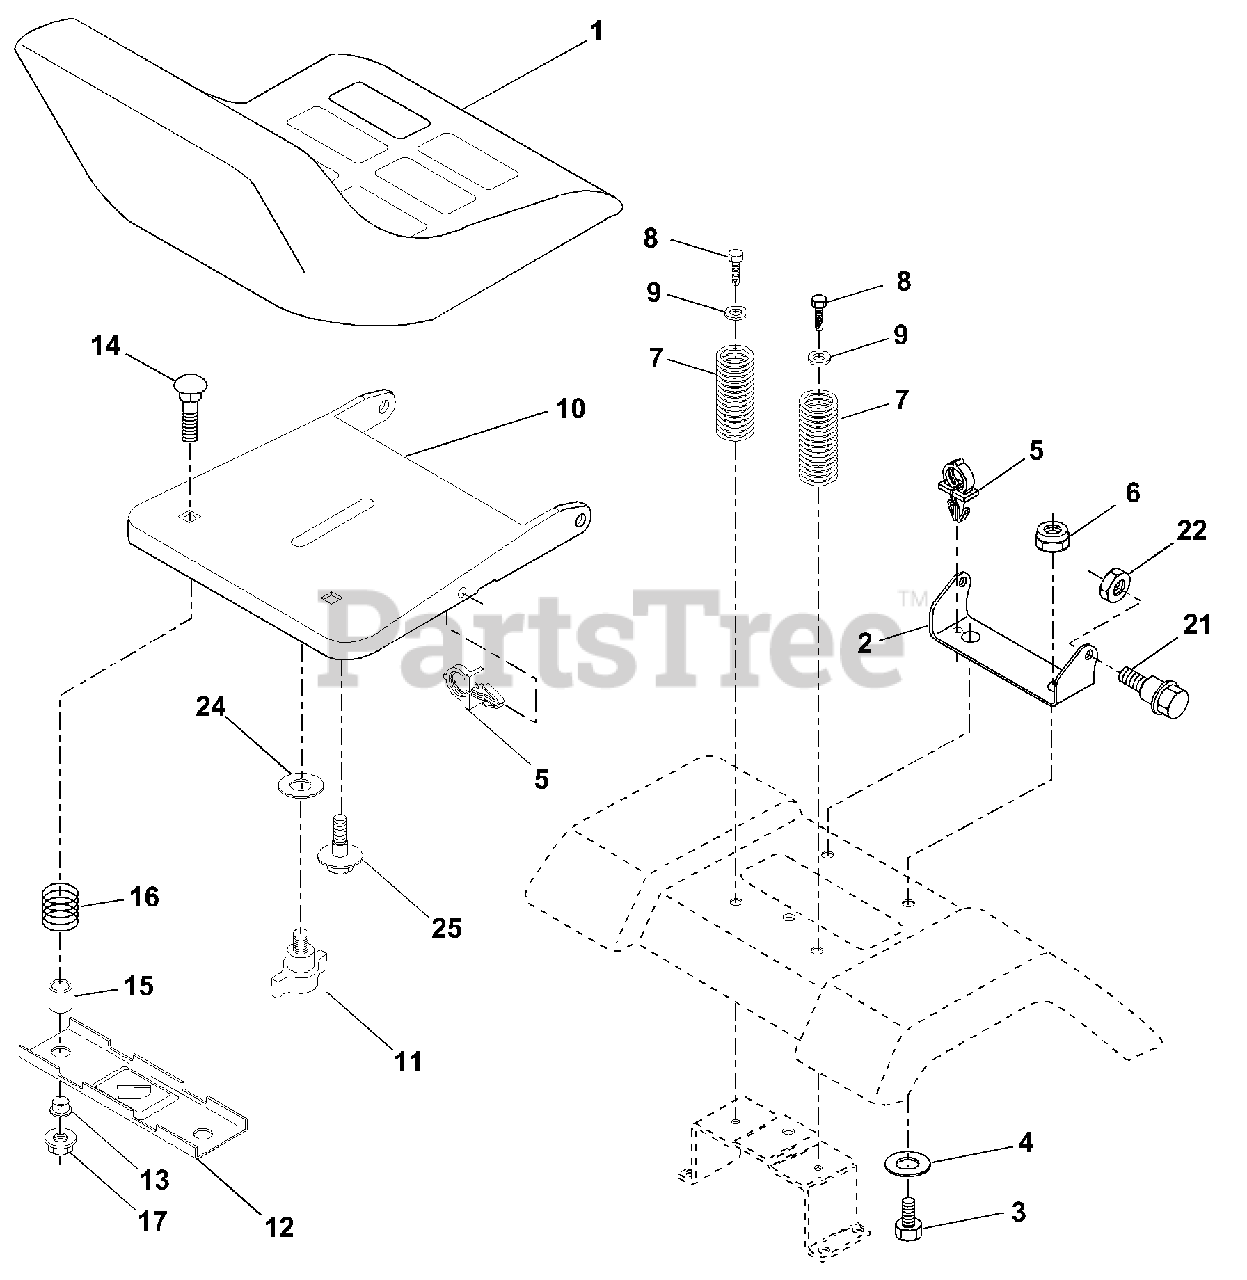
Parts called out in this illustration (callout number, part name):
1	Seat
2	Bracket Pivot Seat 8 720
3	Bolt Fin Hex 3/8-16 Unc x 1
4	Washer Flat 13/32 x 1 x 10 Ga.
5	Clip Push-In
6	Nut Hex w/Ins. 3/8-16 Unc
7	Spring Seat Cprsn 2 250 Blk Zi
8	Screw 3/8-16 x 1
9	Washer 13/32 x 1 x 14 Ga.
10	Pan Seat
11	Knob Seat Adj. Wingnut
12	Bracket Mounting Switch
13	Bushing Snap Blk Nyl 50 Id
14	Bolt Rdhd Sqnk 1/4-20x1-1/2
15	Spacer Split 28x 88
16	Spring Cprsn
17	Nut Lock 1/4 Lge Flg Gr 5 Zinc
21	Bolt Shoulder 5/16-18 Unc
22	Nut Hex Lock W/Ins 5/16-18
24	Washer 17/32 X 1-3/16 X 12 Ga.
25	Bolt Shoulder 5/16-18 X 62
27	Screw Thdrol 3/8-16 x 1/2
28	Bolt 5/16-18 Unc x 3/4 w/Sems
